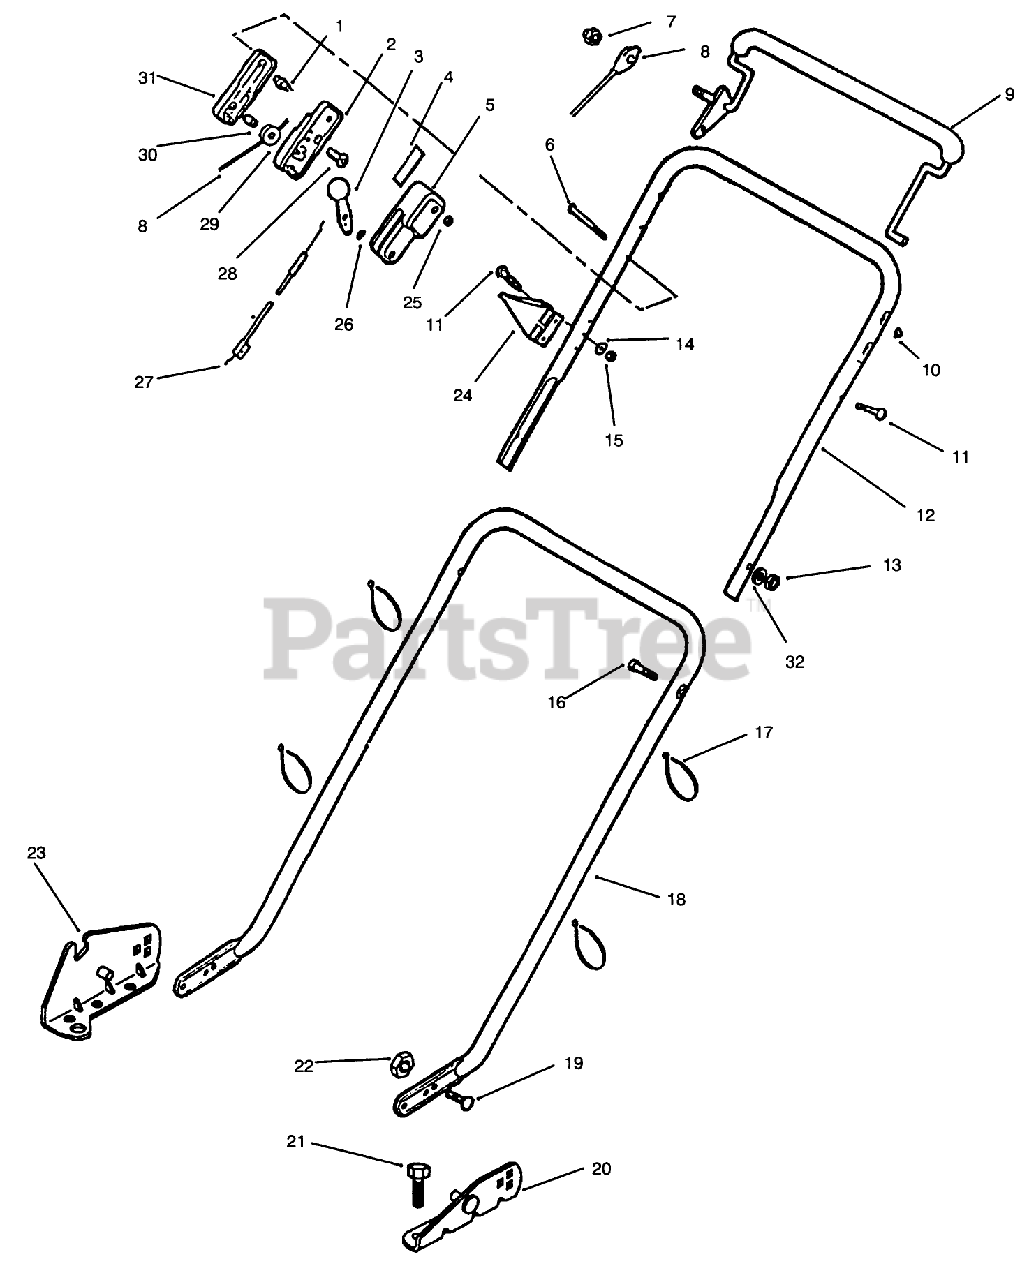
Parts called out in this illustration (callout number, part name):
3	LEVER&KNOB AY WES
7	NUT ACORN
8	CONTROL CABLE
9	CONTROL LEVER ARG
13	NUT-LOCK, NI
15	NUT-LOCK, NI
16	SCREW-HH
17	TIE-CABLE
22	NUT-LOCK, NI
25	NUT-LOCK, NI
26	WASHER-SPRING
27	CABLE TH'TTLE WES
29	PULLEY PL
30	PIN SKF
31	OUTER CONTROL CASE
32	WASHER-CURVED
